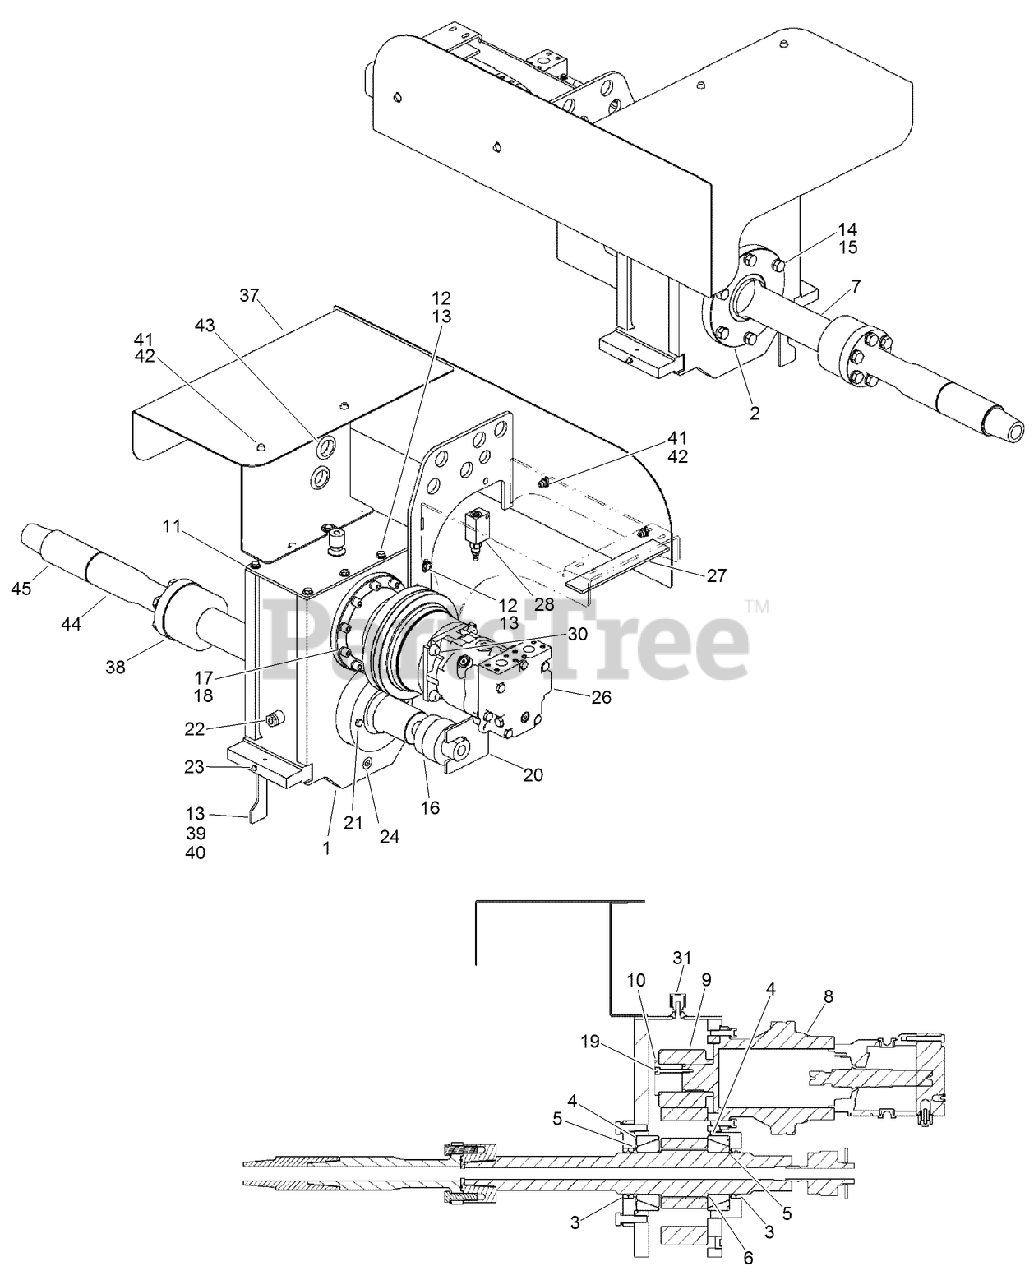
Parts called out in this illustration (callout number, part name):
1	BOX - Rotary
2	CAP-BEARING, ROTARY
3	SEAL-SHAFT
4	CUP-BEARING
5	CONE-BEARING
6	GEAR-RING, ROTARY
7	SPINDLE-ROTARY
8	PLANETARY GEARBOX ASM
9	PINION-ROTARY
10	CAP-PINION, ROTARY
11	PLATE-TOP, ROTARY BOX
12	WASHER - Flat, 3/8 ZN Pltd
13	SCREW-HH
14	WASHER - Split Lock, 5/8
15	SCREW-HH
16	SWIVEL-MUD
17	WASHER - Split Lock, 1/2 x 0.175 Thk
18	SCREW-HSFH
19	SCREW-HSH
20	BRACKET - Mud Swivel
21	CAPSCREW - Hex Hd, 3/8 - 16 x 3/4
22	PLUG-SITE, GLASS
23	FITTING - Lube, 1/8 NPT x 11/16 Long
24	PLUG-MAGNETIC, HEX
26	HYD MOTOR ASM
27	MOUNT - Hose Carrier, Rotary
28	VALVE-RELIEF, PRESSURE
30	SCREW-HFH
31	BREATHER
37	GUARD - Carriage
38	SPINDLE ASM
39	PLATE - Proximity Trigger
40	WASHER-Spring Lock, Reg 3/8 ZND
41	SCREW-HH
42	NUT-TORQUE, PREVAILING
43	GROMMET - Rubber, 1.5 ID
44	ADAPTER-FLANGE
45	SAVER ASM
